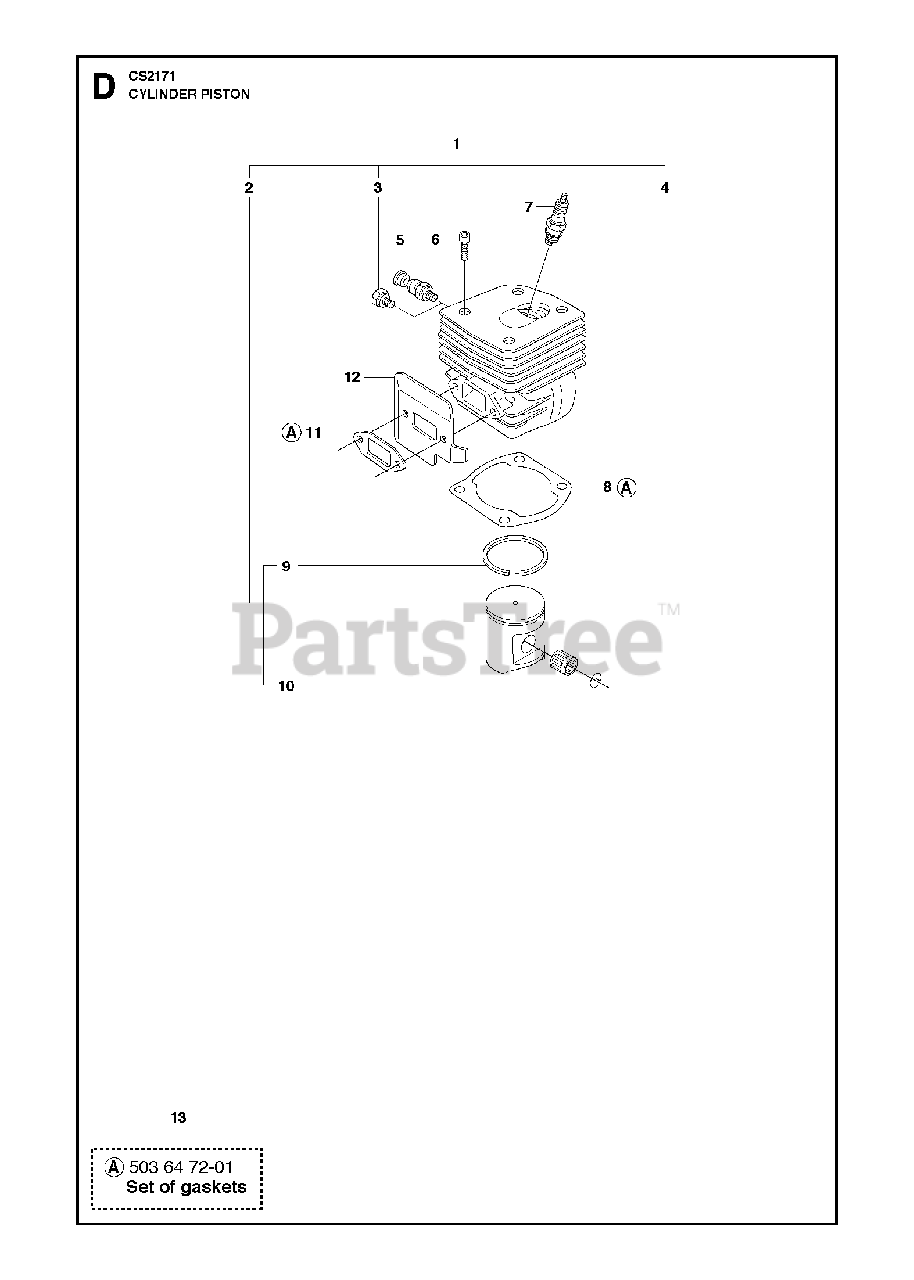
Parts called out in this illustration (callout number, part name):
1	%CYLINDER ASSY
1	CYLINDER ASSY
2	PISTON ASSY
2	PISTON CPL 50 MM
3	CYLINDER PLUG
4	SUPPORT BUSHING
5	DECOMPRESSION VALVE
6	SCREW MC6S 5X25
7	SPARK PLUG RCJ7Y
8	GASKET
9	PISTON RING
9	RP PISTON RING
11	GASKET
12	DEFLECTOR
13	GASKET SET
